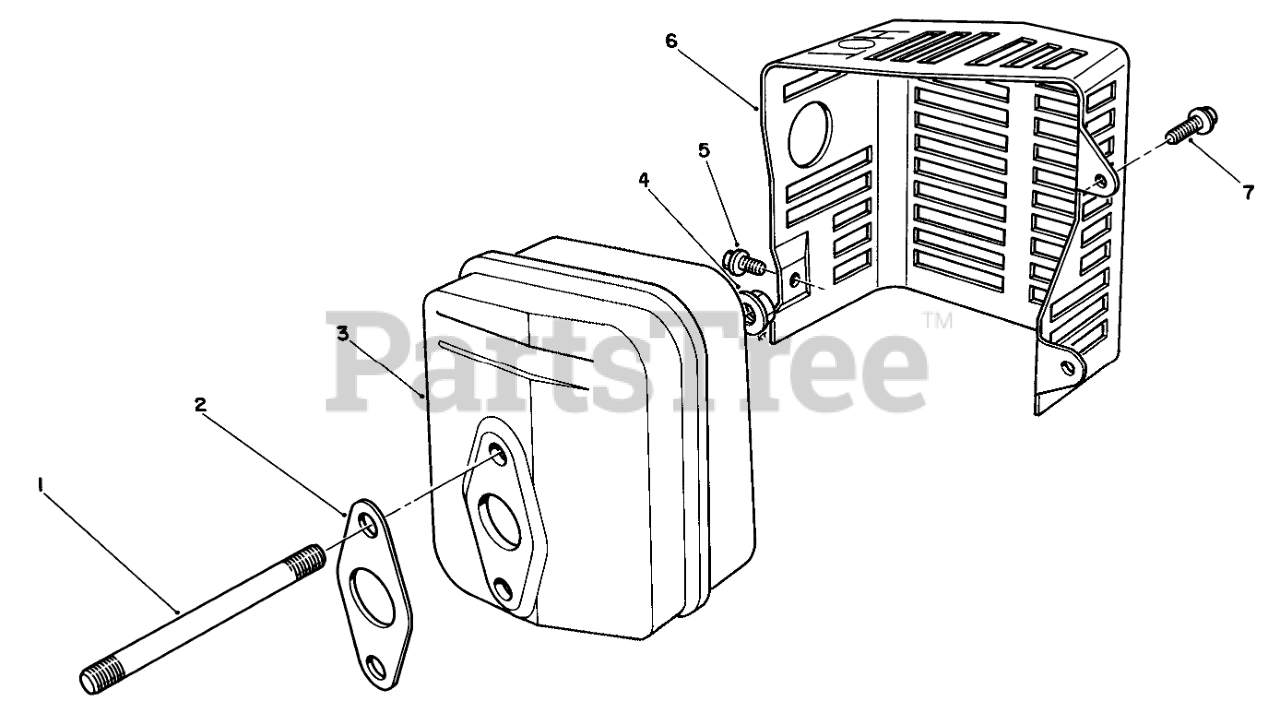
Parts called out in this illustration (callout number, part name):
2	GASKET
3	MUFFLER
5	SCREW
6	COVER
